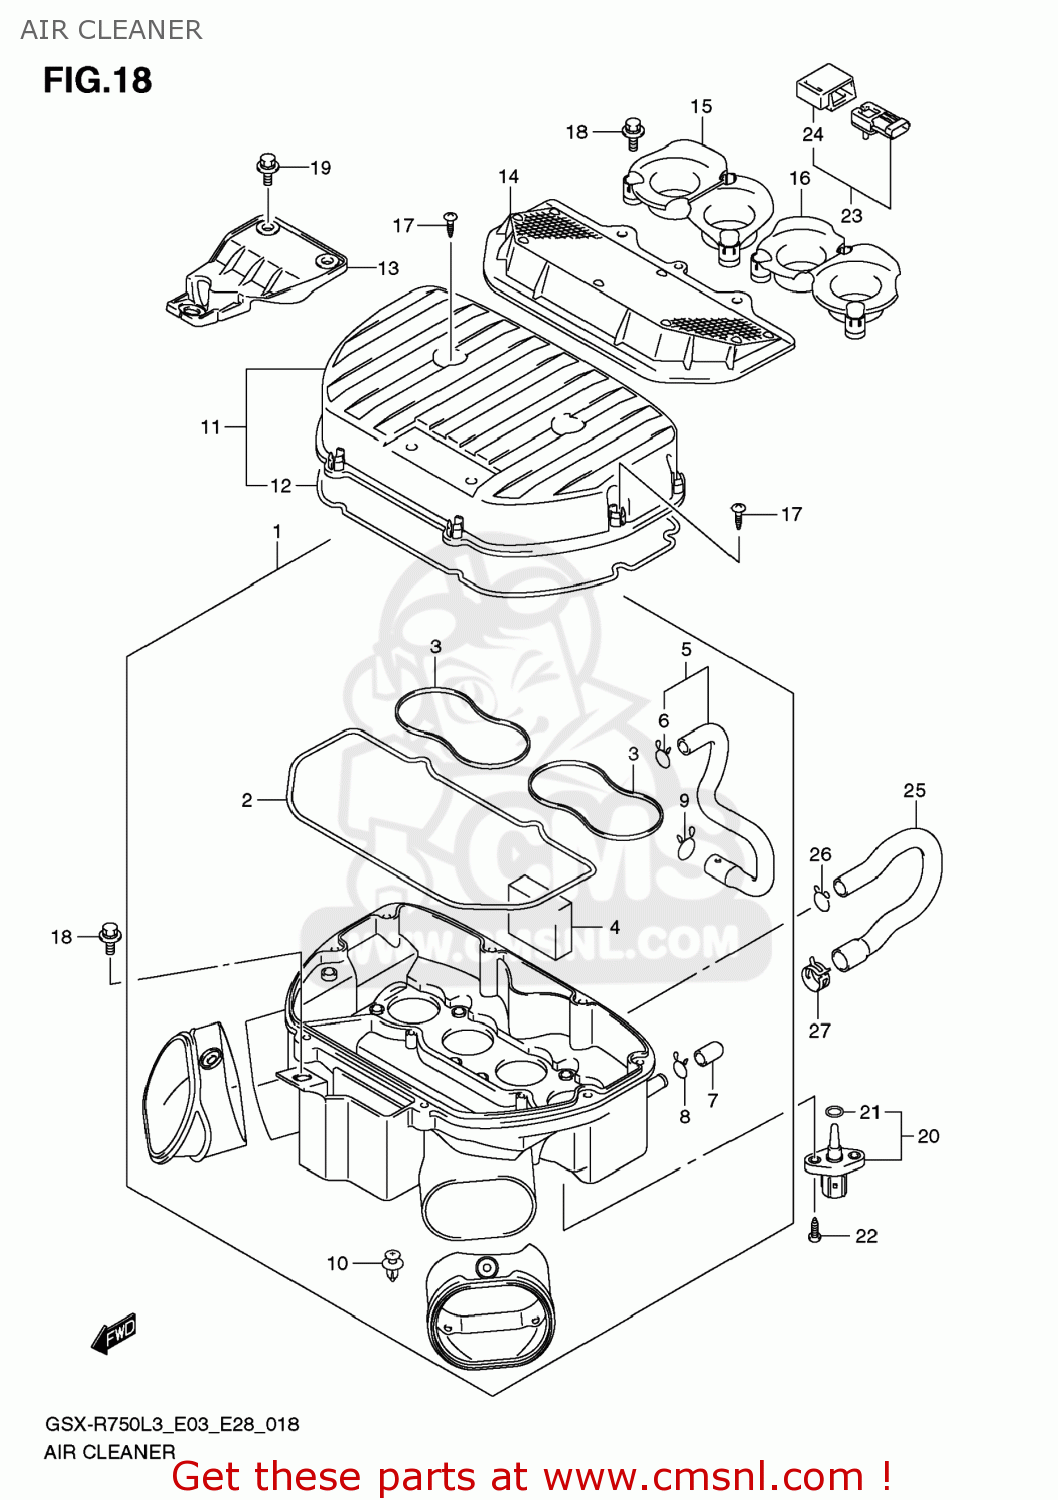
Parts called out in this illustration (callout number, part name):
1	CASE,AIR CLEANER
2	GASKET,CASE (NAS)
3	GASKET,CASE (NAS)
4	FILTER,BREATHER
5	TUBE,BREATHER
6	CLIP
7	PLUG
8	CLIP
9	CLIP
10	CLIP(BLACK)
11	CAP,AIR CLEANER
12	GASKET,CAP (NAS)
13	HOLDER,AIR CLEANER
14	FILTER ASSY
15	FUNNEL,OUTLET,R
16	FUNNEL,OUTLET,L
17	SCREW
18	BOLT,AIR CLEANER CASE
19	BOLT(6X16)
20	SENSOR,AIR TEMP
21	O RING
22	SCREW
23	SENSOR,AIR PRESSURE
24	COVER
25	HOSE
26	CLIP
27	CLIP
